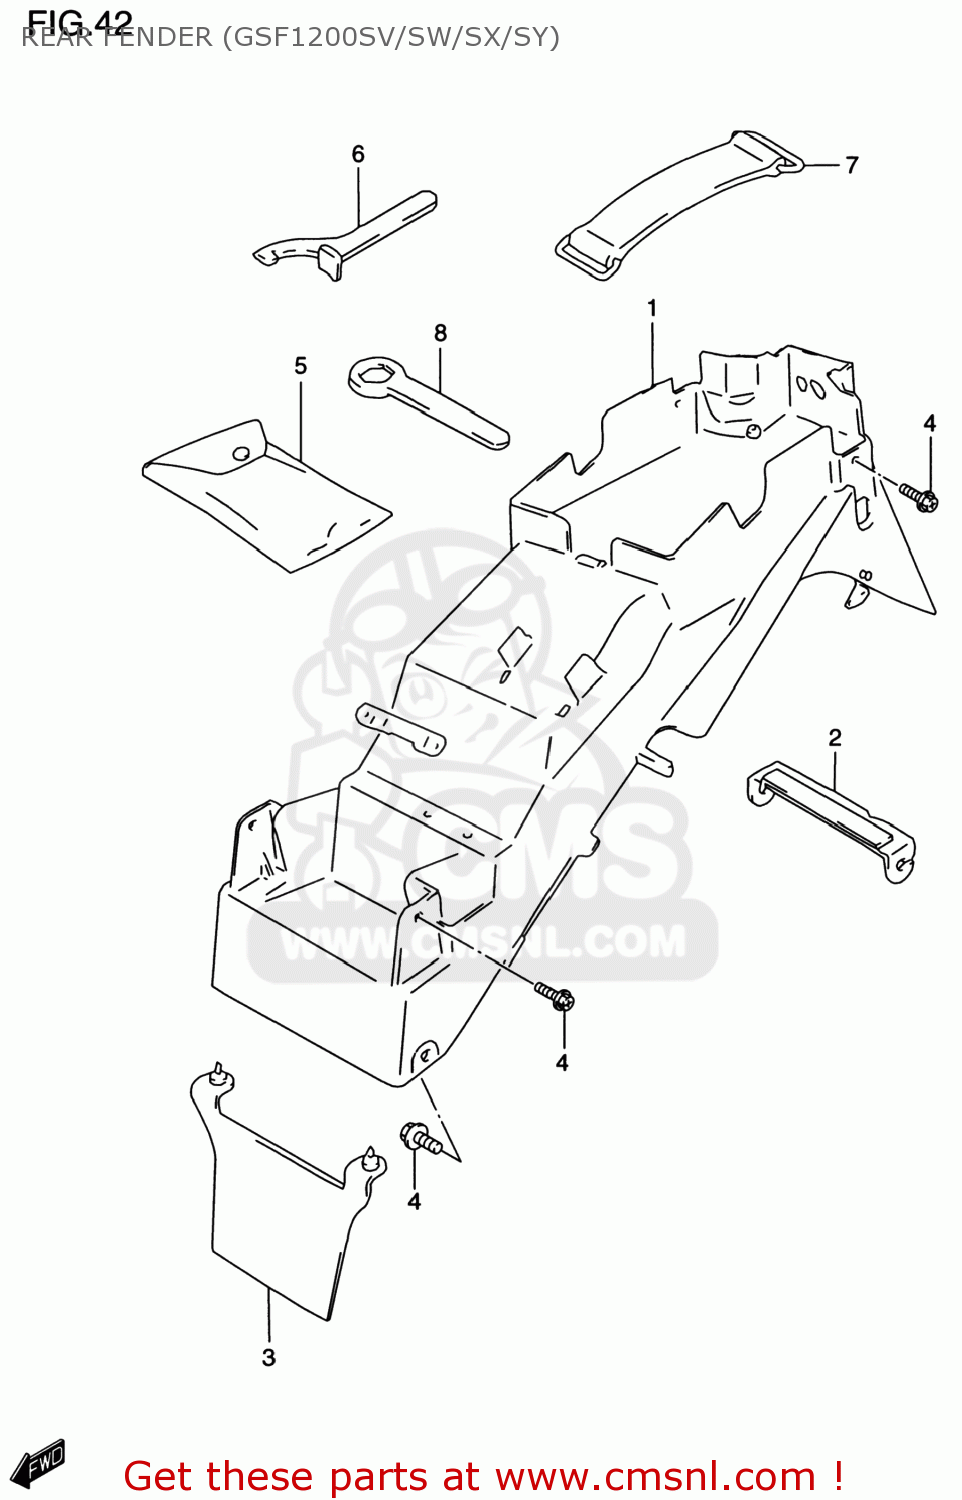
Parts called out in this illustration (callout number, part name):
1	FENDER,REAR
2	REINF,RR FENDER
3	MUDGUARD,RR FENDER FR
4	BOLT(6X16)
5	TOOL ASSY
6	CLAMP
7	BAND
8	RING,SPANNER(24)
